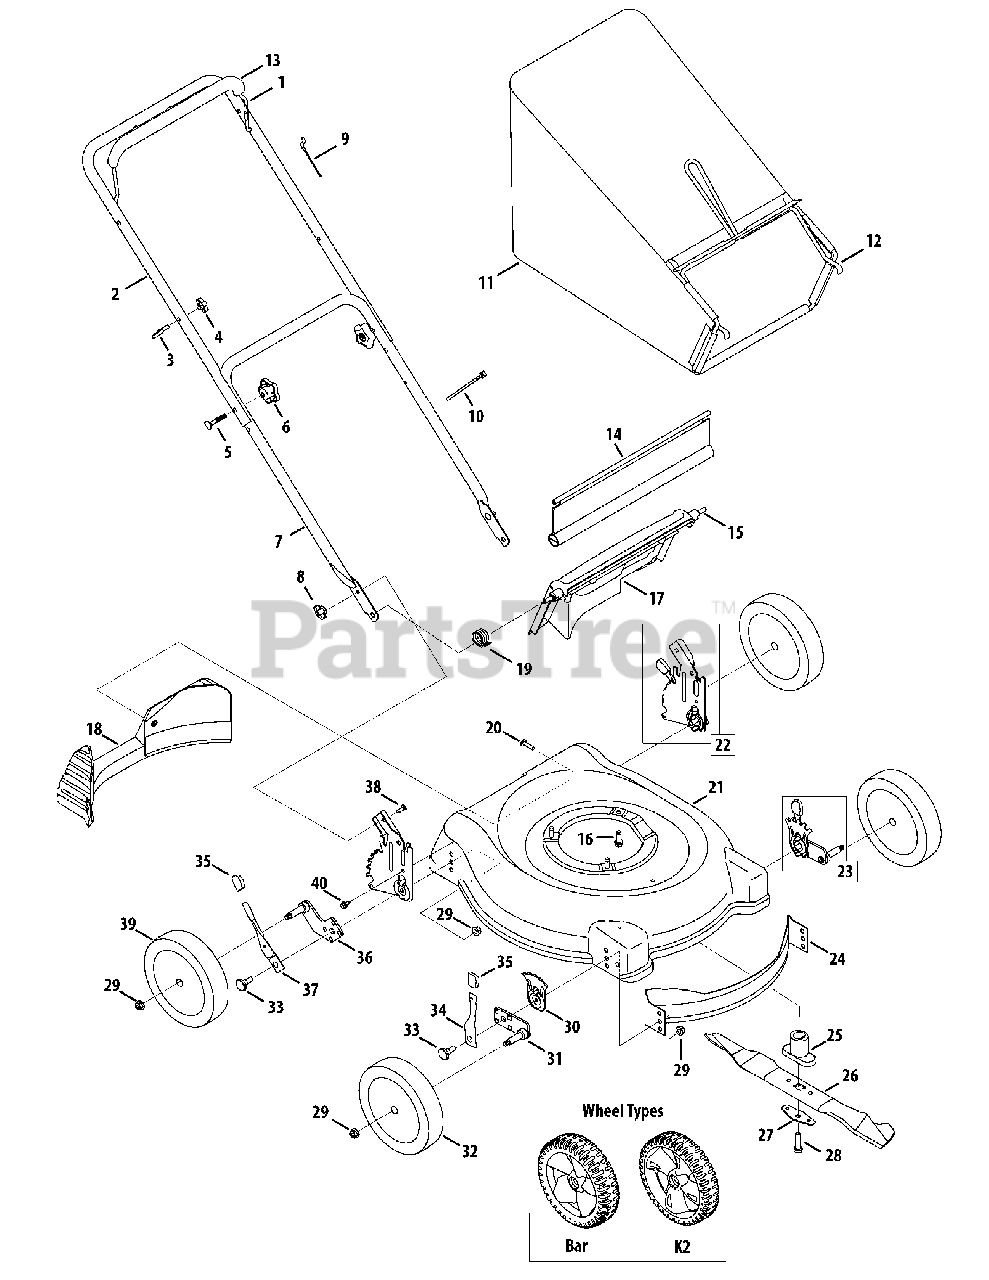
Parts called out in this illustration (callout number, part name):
1	Blade Control
2	Upper Handle
3	Rope Guide
4	Wing Nut, 1/4-20
5	Carriage Bolt, 5/16-18 x 2
6	Hand Star Knob
7	Lower Handle
8	Wing Nut, 1/4-20
9	Control Cable - 37.25"
10	Cable Tie
11	Grass Bag
13	Bail Cover
14	Trailshield
15	Rear Door Pivot Rod
16	TT Screw, 3/8-16 x 1
17	Rear Discharge Door
18	Rear Baffle
19	Torsion Spring RH
20	Screw, 1/4-15 x 1.00
21	Deck 21 inch
22	Handle Bracket Assy - RH
22	Handle Bracket Assy - LH
23	Ht. Adj. Assy. Frt - LH (7" Wheel)
23	Ht. Adj. Assy. Frt - RH (7" Wheel)
24	Front Baffle
25	Blade Adapter, #6 x 2.15
26	Standard Blade
26	Mulch Blade
27	Blade Bell Support
28	Screw, 3/8-24 x 2.50
29	Flange Lock Nut, 3/8-16
30	Height Adjustment Plate
31	Pivot Arm Assy RH (7" wheel) Front
31	Pivot Arm Assy LH (7" wheel) Front
32	Wheel, 7 x 1.8, Spoke Bar Front
33	Shoulder Screw
34	Spring Lever Front
35	Height Adjustment Knob
36	Pivot Arm Assembly - RH Rear
36	Pivot Arm Assembly - LH Rear
37	Spring Lever Rear
38	Carriage Bolt, 1/4-20
39	Wheel, 8 x 1.8, Spoke Bar Rear
40	Screw, 1/4-20 x .625
